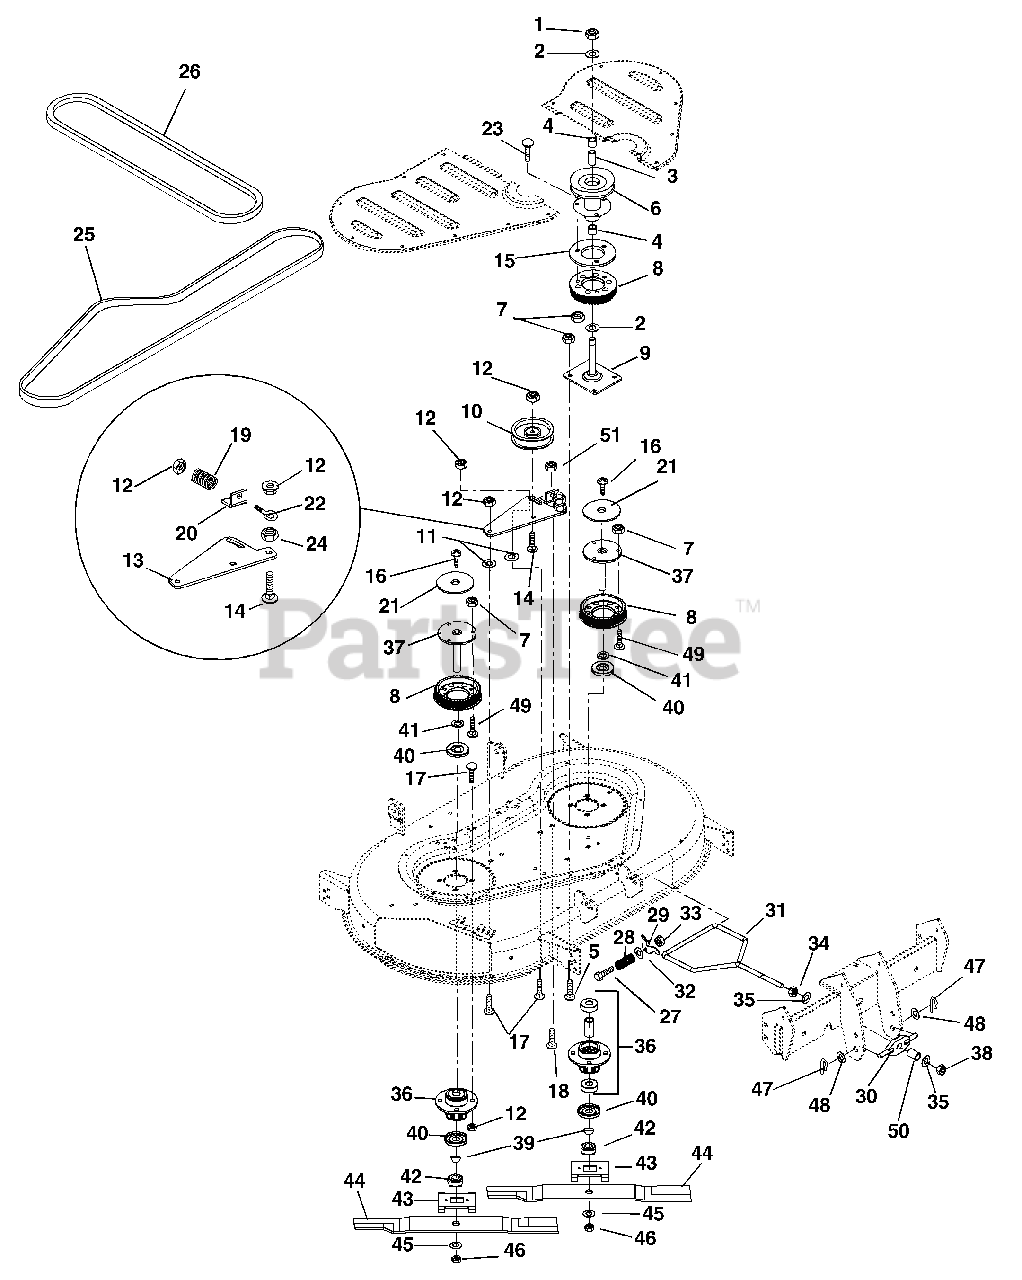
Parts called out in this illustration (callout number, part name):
1	@NUT-LK-NYL .625-18 YWZC
2	WSHR-FL-STL .630X1.005X.062 YZ
3	SPACER, .640X.88X4.069
4	BRG-BALL .625X1.375X.43
5	@BLT-RDHDSQNK .31-18X.75 G5YZ
6	JACKSHAFT - EZR
7	@NUT-LK-TOP-FLG .31-18 YWZC
8	SPROCKET, DRIVE
9	WELDMENT, PLATE MOUNT
10	IDLER, FLAT .377X4.0X.96W POLY
11	WSHR-FL-STL .38"X1.5"X.188"
12	@NUT-LK-TOP-FLG .38-16 YWZC
13	ARM, BELT ADJUSTMENT
14	@BLT-RDHDSQNK .38-16X1.75 G5YZ
15	SPACER, SPROCKET
16	SCR-TAP .25-20X.75 HWH TR YWZ
17	@BLT-RDHDSQNK .38-16X1.25 G5YZ
18	@BLT-RDHDSQNK .38-16X.75 G5YZ
19	SG-COMP .125X.781X1.250
20	BRACKET, BELT ADJUSTMENT
21	RETAINER, BELT
22	BLT-EYE .375-16X2.50 YWZC
23	@BLT-RDHDSQNK .31-18X1.25 G5YZ
24	@NUT-LK-NYL .38-16 YWZC
25	COG-BELT X8M
26	V-BELT, 5L-WRAPPED
27	@BLT-HEX .25-20X1.25 GR5 YWZC
28	SG-COMP .058X.68X.75
29	RETAINER, BRACE
30	WELDMENT, FRONT MOUNT
31	ROD, LINK
32	@WSHR-FL-STL.312X.734X.065 YWZ
33	@NUT-LK-NYL .250-20 YWZC
34	@NUT-LK-CTR .50-13 YWZC
35	@WSHR-FL-STL.563X1.38X.109YWZC
36	ASSEMBLY, SPINDLE HOUSING
37	WELDMENT, SPINDLE SHAFT
38	@NUT-LK-NYL .50-13 YWZC
39	KEY-WDRF .188X.625X.31 SAE9MOD
40	BEARING SLINGER
41	WSHR-FL-STL .755X1.25X.125 YZ
42	HUB, RETAINER
43	TRAY, BLADE
44	BLADE, 22"
44	BLADE, 22" LOW LIFT - CE
45	@WSHR-LK .75X.188 REG YWZC
46	NUT-JAM .75-10 YWZC
47	CLIP, SPRING
48	@WSHR-FL-STL.531X1.06X.095YWZC
49	@BLT-RDHDSQNK .31-18X1.00 G5YZ
50	BSHG-SLV .50X.74X.53
51	@NUT-LK-CTR-JAM .375-16 YWZC
